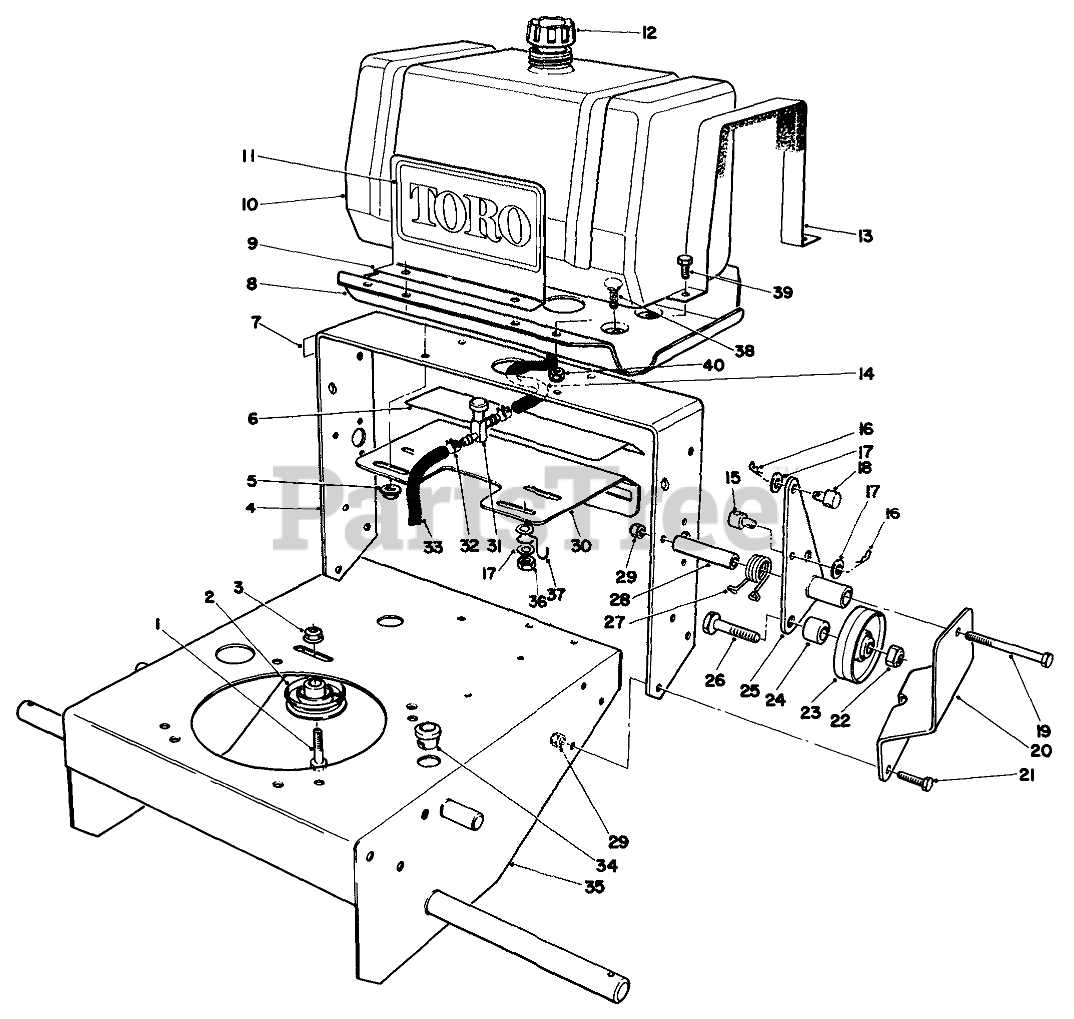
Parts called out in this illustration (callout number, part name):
1	SCREW-HH
2	PULLEY-IDLER
3	NUT-HF
4	Frame-Rear
5	NUT-HF
6	Decal-Ground Speed
7	Decal-Fuel Shut Off
8	PLATE-FUEL TANK
9	DECAL-PLATE
10	TANK-FUEL
11	DECAL
12	CAP-FUEL ASM
13	STRAP ASM
14	HOSE-FUEL
15	ROD FITTING
16	PIN-COTTER
17	WASHER-PLAIN
18	ROD FITTING
19	SCREW-HH
20	Support-Idler L.H.
21	SCREW-HH
22	NUT-LOCK, NI
23	IdlerWheel
24	WHEEL IDLER SPACER
25	LH IDLER BRKT WA
26	SCREW-LEVELER
27	SPRING-TORSION, LH
28	PIVOT-IDLER SPACER
29	NUT-LOCK, NI
30	CONTROL PLATE R
31	FUEL VALVE
32	CLAMP-HOSE
33	HOSE-FUEL
34	GROMMET
35	Frame
36	NUT-LOCK, NI
37	GAS LINE CLIP
38	SCREW-CARR
39	SCREW-HH
40	NUT-LOCK, NI
